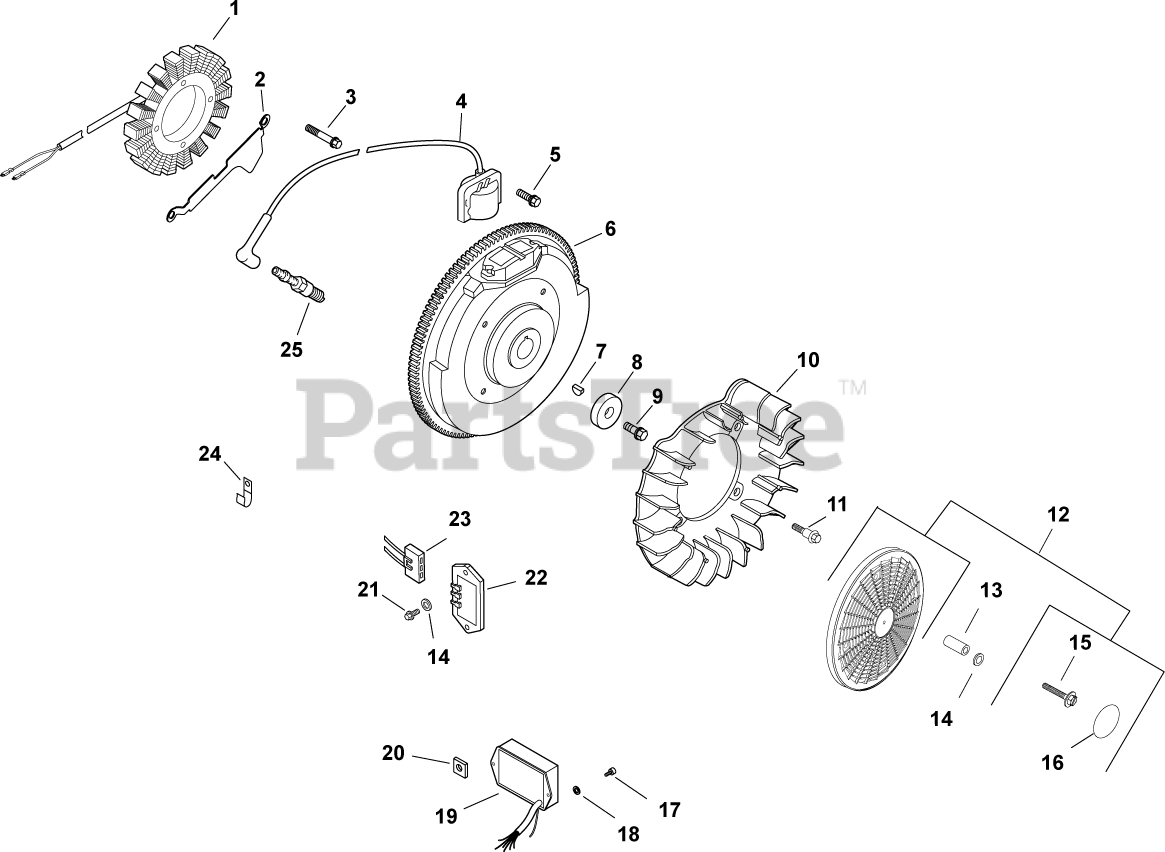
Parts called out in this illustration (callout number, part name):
1	KIT, 15 / 20 AMP STATOR
2	BRACKET, STATOR WIRE
3	SCREW, M5X0.8X25 - (#25086402S)
4	MODULE, IGNITION
5	SCREW, SKT THD FRM M5X0.8X25
6	FLYWHEEL, PAINTED-USE 24 025 57-S
7	KEY, 3/16" X 5/8"
8	WASHER, FLAT 13/32"
9	SCREW, FLG M10X1.5X45 - (#25086361S)
10	FAN USE 24 157 11-S
11	BOLT, SHOULDER
12	KIT, GRASS SCREEN
13	SPACER - DISCONTINUED
14	WASHER, FLAT 3/16"
15	SCREW, SLT HD CAP M4X0.7X25
16	DECAL, GRASS SCREEN USE 24 113 499-S
17	SCREW, PHL HD #11-16X1/2"
18	WASHER, FLAT 1/4" (O.D. 1/2")
19	MODULE, SPEED ADVANCE-DISCONTINUED SEE PB265
20	NUT, PLASTIC
21	SCREW, PHL HD #11-16X7/8"
22	REG/RECT-15 AMP (KM)-USE 41 403 10-S
23	PLUG, SPARK (STD)
24	CLIP, CABLE
25	CONNECTOR, BODY (KM)-USE 25 155 41-S
2545403-S	TIE, WIRE
